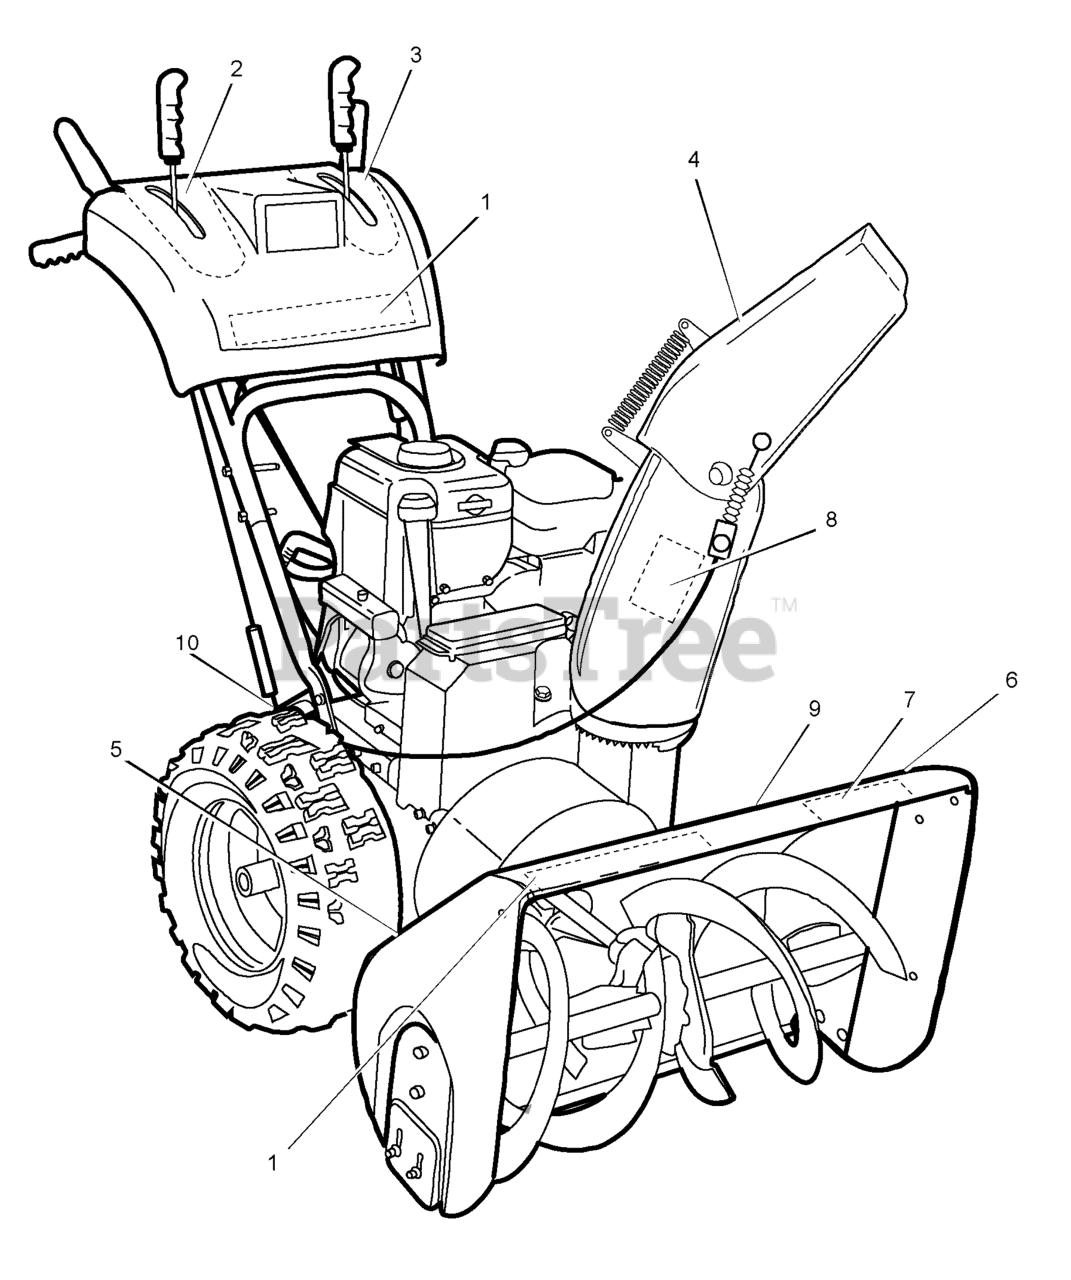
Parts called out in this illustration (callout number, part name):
1	DECAL, CANADIANA
2	DECAL, CANADIANA 1350/74 HYDRO
3	DECAL, REMOTE CHUTE TRACTION
4	DECAL, ISO CHUTE
5	DECAL, ISO AUGER
6	DECAL, FACE HEAD PHONES
7	DECAL, 1350/74 TOP AUGER WHITE
8	DECAL, HYDRO SIDE OF CHUTE
9	DECAL, 104db CE
10	DECAL, ID PLATE
